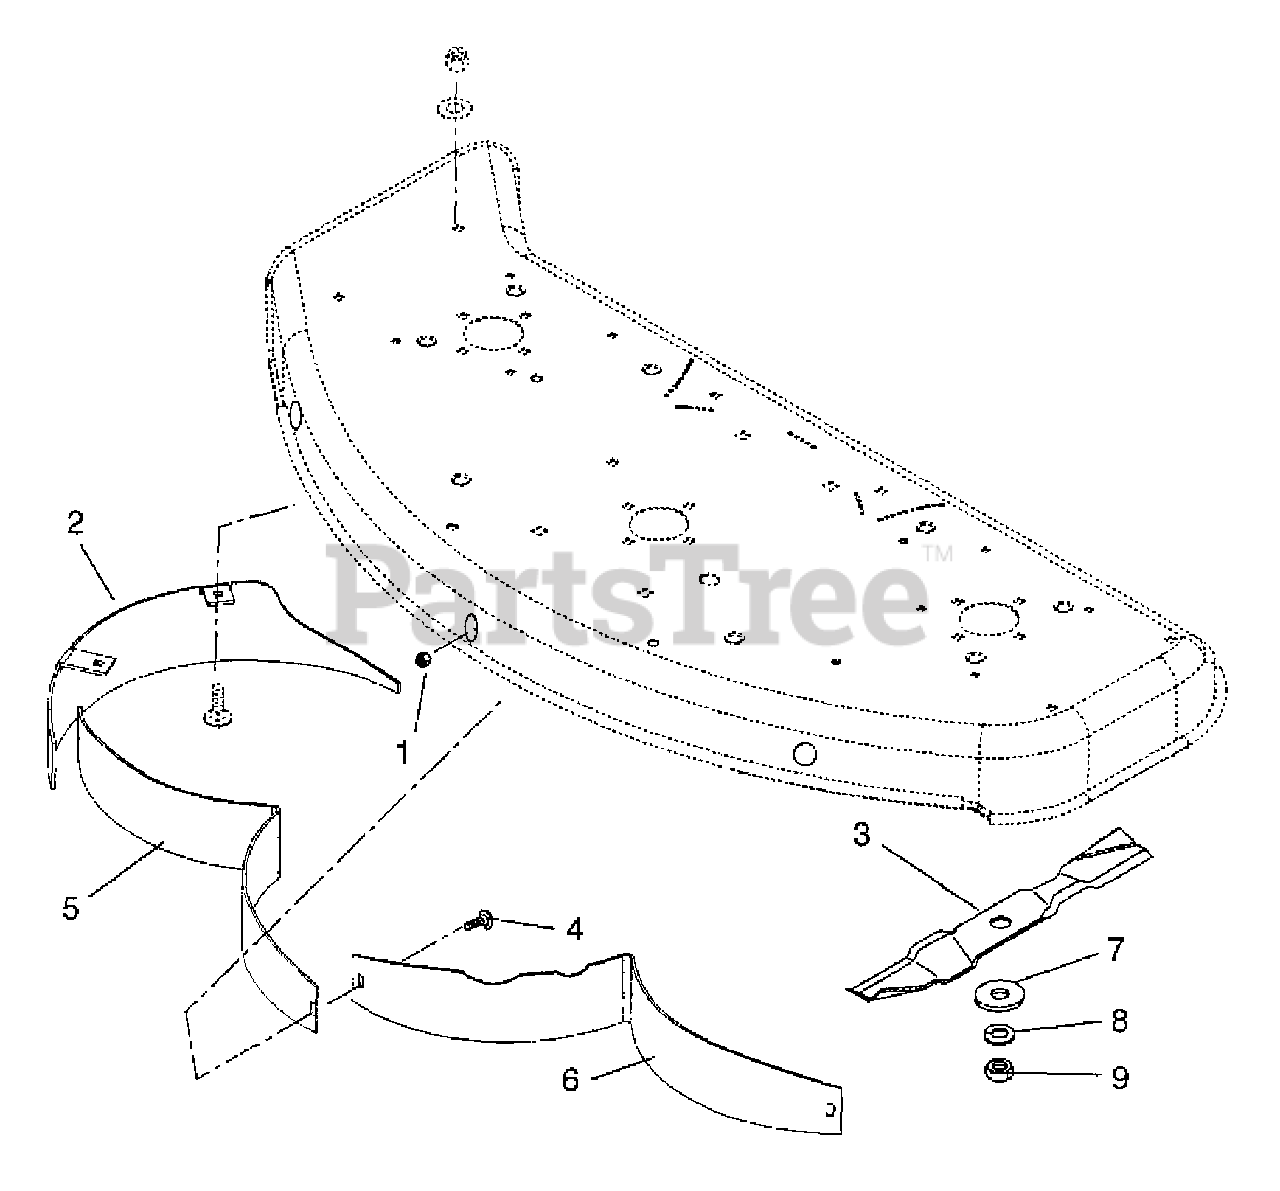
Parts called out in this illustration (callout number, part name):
1	Nut-Locking-Nylon .312-18
2	Weldment-Chute Baffle
3	Blade-Mulching 50" Mower
4	Bolt-Round Head Square Neck .31-18 x .75
5	Baffle, Mulching-RH
6	Baffle, Mulching-LH
7	Washer-Flat-Steel .640 x 1.81 x .250
8	Washer-Locking .62 x .156
9	Nut-Locking-Center .62-11
